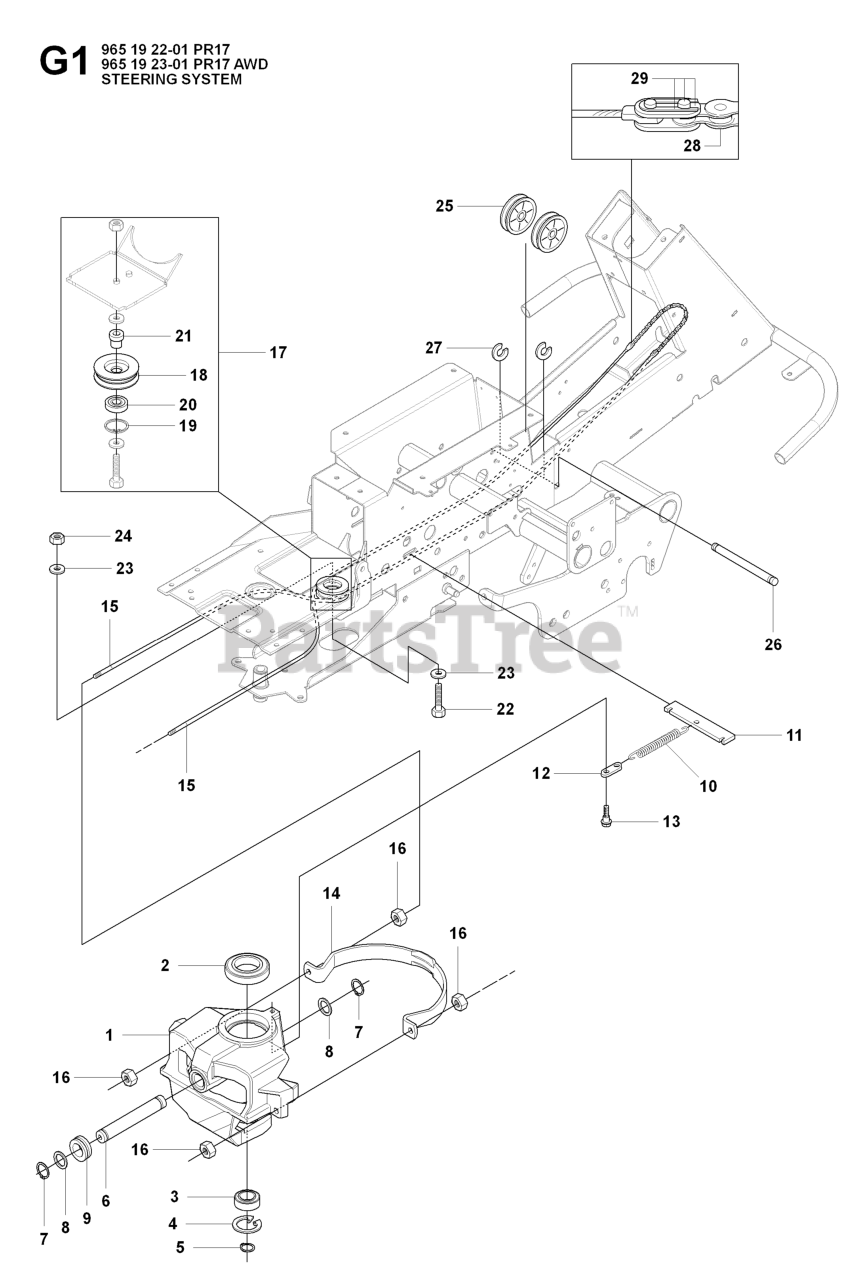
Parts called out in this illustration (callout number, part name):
2	BALL BEARING 6010 2RS1
3	Ball Bearing 6005-2rs
4	CIRCLIP SGH 47
5	RETAINING RING SGA 25
7	RETAINING RING SGA 25
11	SPRING BRACKET
14	WIRE GUIDE
15	RP STEERING CABLE COMPLETE
16	NUT
19	CIRCLIP SGH 47
20	BALL-BEARING 6204-2RS
22	REPL BY 725 25 00-71
24	NUT
26	RP PIN
27	RETAINING RING
28	STEERING CHAIN
